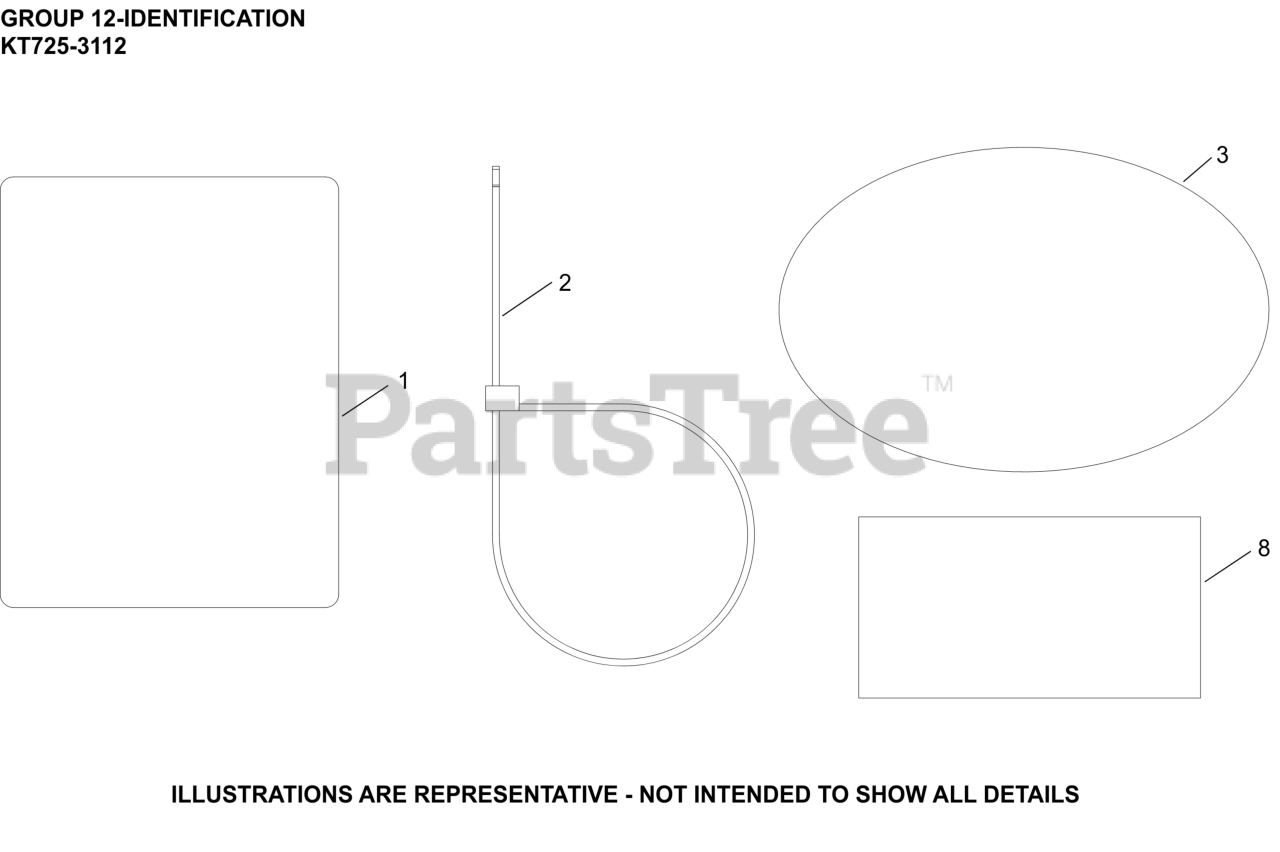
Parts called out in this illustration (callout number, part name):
1	LABEL, CLEAR LAMINATION
3	LABEL, 7000 SERIES KT725 (22 HP)
8	DECAL, USA
